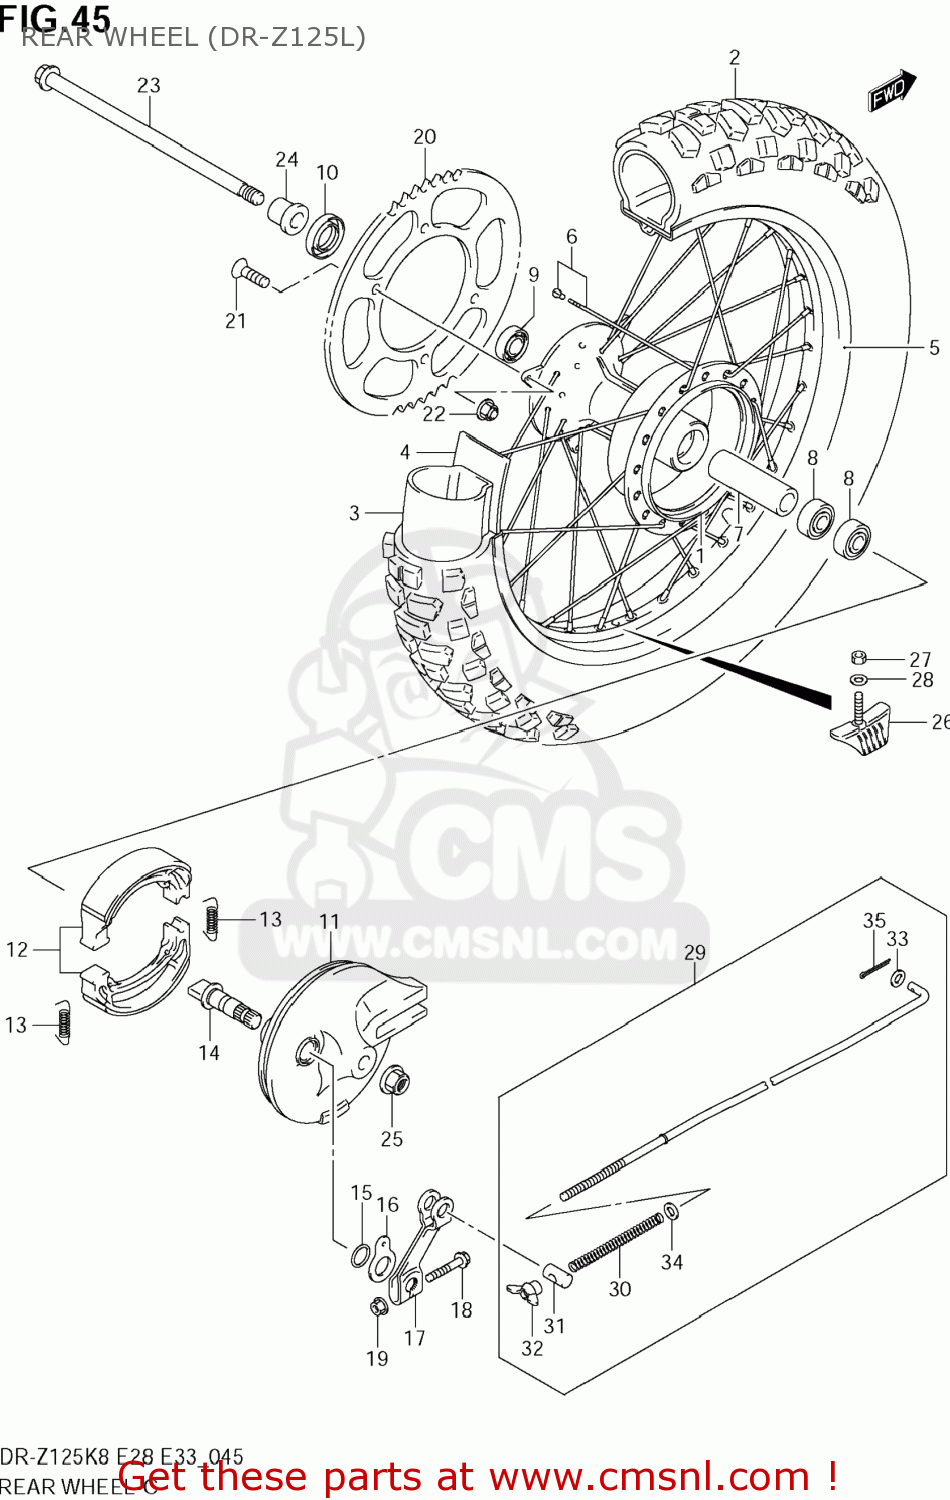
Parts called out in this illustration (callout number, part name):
1	HUB,RR WHEEL
2	TIRE,RR
3	TUBE ASSY,WHEEL INNER
4	PROTECTOR,WHL INR TUBE
5	RIM,RR WHEEL(16X1.60)
6	SPOKE SET,RR WHEEL
7	SPACER(12.5X19X45.5)
8	BEARING
9	BEARING
10	SEAL,OIL(20X37X7)
11	PANEL,RR BRAKE ANCHOR
12	SHOE SET,BRAKE (NAS)
13	SPRING
14	CAM,RR BRAKE
15	O RING(D:2.5,ID:13.8)
16	PLATE,BRAKE LINING INDICATOR
17	LEVER,RR BRAKE CAM
18	BOLT
19	NUT
20	SPROCKET,RR(57T-428)
21	BOLT(8X30.5)
22	NUT
23	AXLE,RR
24	SPACER,RR AXLE
25	NUT
26	STOPPER,BEAD
27	NUT
28	WASHER
29	ROD ASSY,RR BRAKE
30	SPRING
31	PIN(11X18)
32	NUT
33	WASHER
34	WASHER
35	PIN
